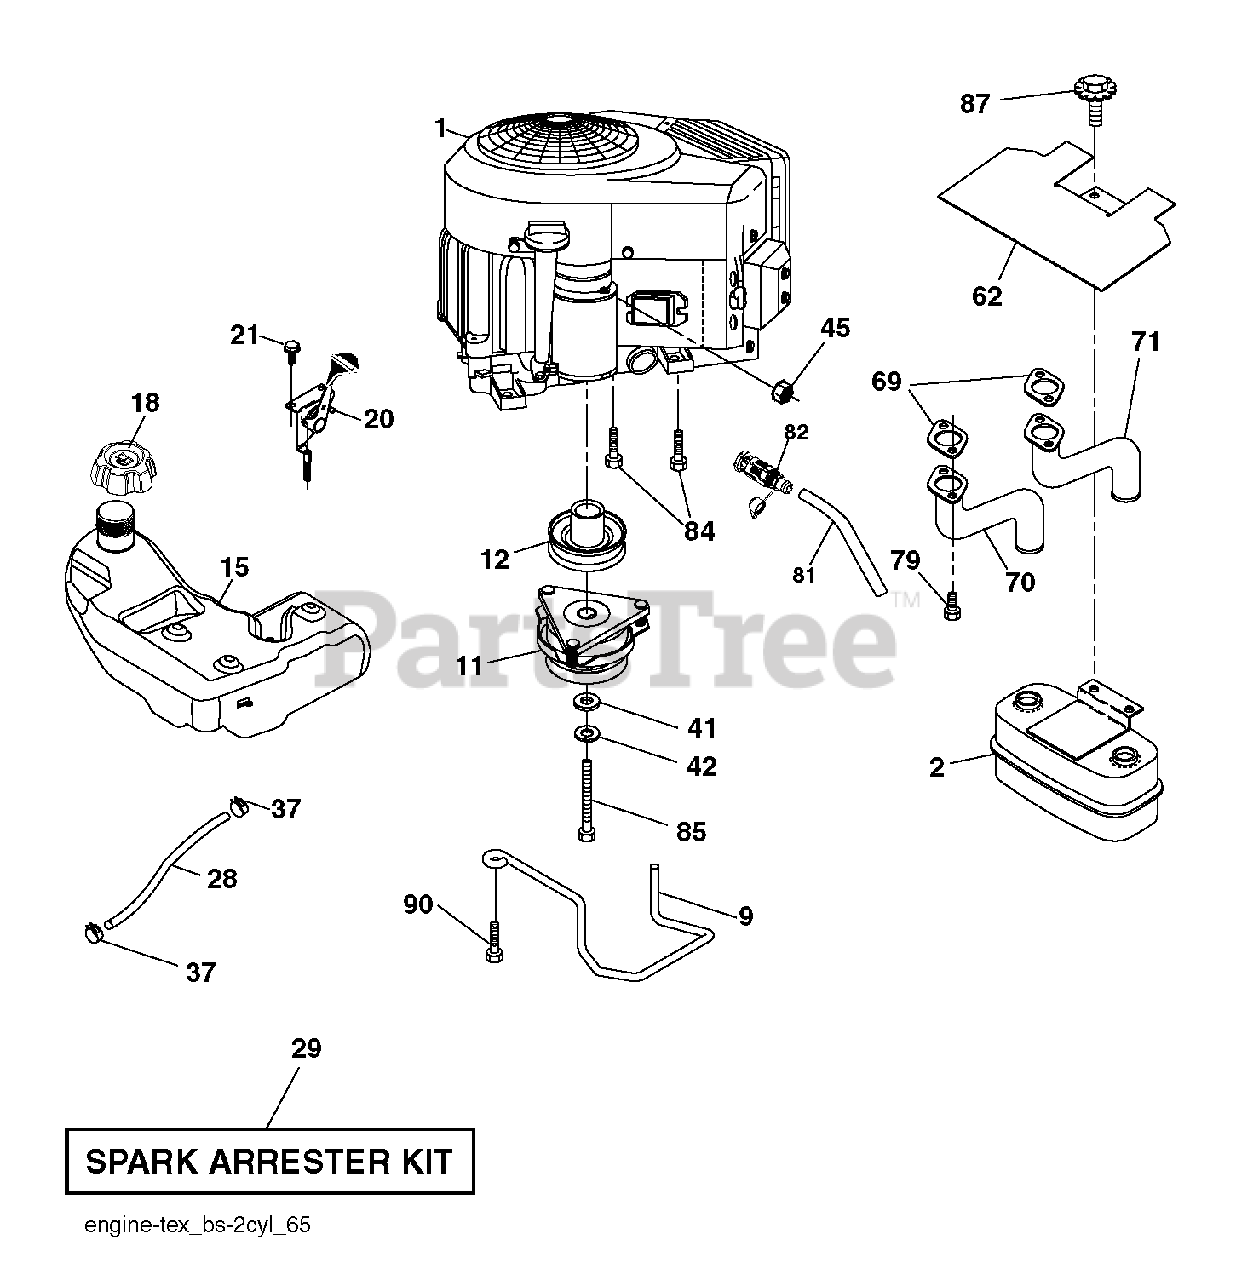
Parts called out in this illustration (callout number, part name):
2	MUFFLER.TWIN.CYL.LOW.TONE
9	KEEPER.BELT.ENGINE.4.2
11	CLUTCH ELECTRIC
12	PULLEY ENGINE
15	TANK.FUEL.4GAL
18	CAP.ASM.FUEL.TANK.3"BLACK
20	CONTROL.TH/CK.COBRA.B&S.TWN.
21	SCREW.#10 X 0.750.BOS (2 2)
28	LINE.FUEL.64"REAR.EMIS
29	KIT.SPARK ARRESTOR(392390 B&S)
37	HOSE CLAMP
42	LOCKWASHER
45	NUT
62	SHIELD.HEAT.MUFFLER
69	GASKET.MUFFLER
70	RP.EXHAUST.TUBE.LH.BS/TWIN
71	RP.EXHAUST.TUBE.RH.BS/TWIN
79	SCREW.SOCKET.HEAD.5/16-18
81	TUBE, DRAIN OIL ASM.
82	VALUE.OIL.DRAIN
84	SCREW.3/8-16
85	BOLT HEX 7/16-20 X 3.75 GR. 5
87	BOLT.5/16-18UNCX1.W/SEMS.BLK
90	SCREW 3/8-16X1
